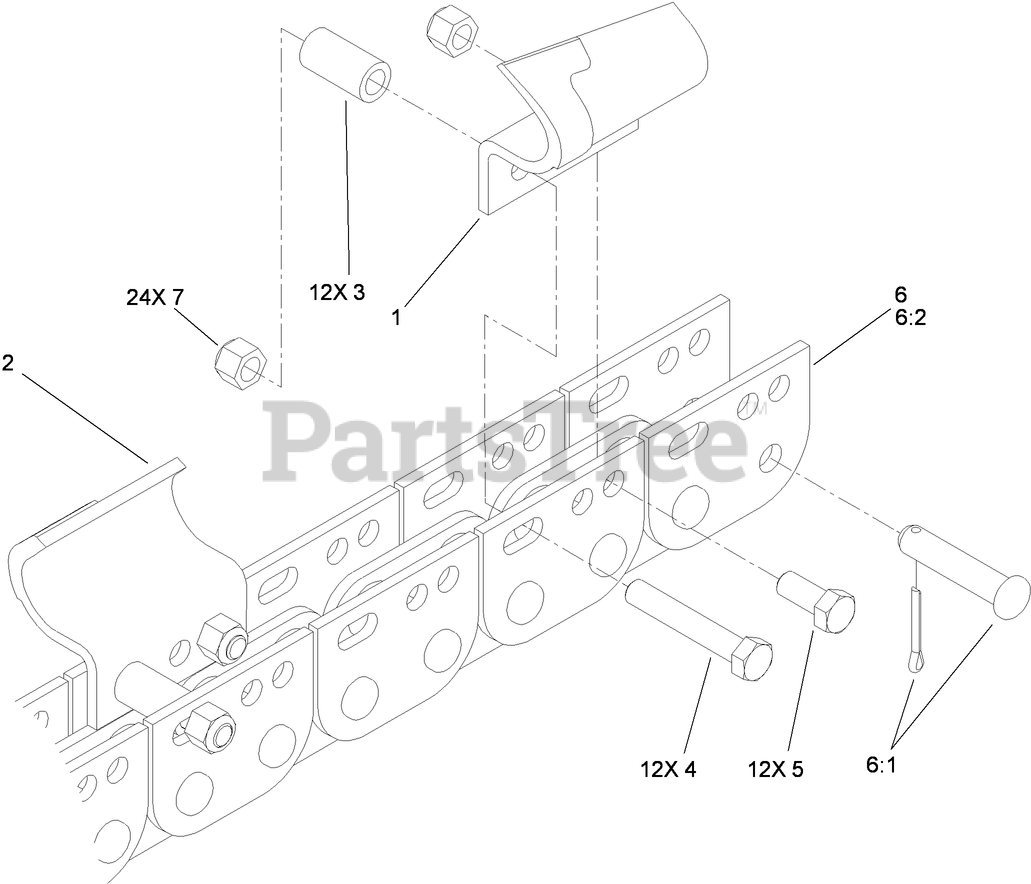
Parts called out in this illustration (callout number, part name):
1	TOOTH-SOIL, LH
2	TOOTH-SOIL, RH
3	SPACER-TUBE
4	SCREW-HH
5	SCREW-HH
6	CHAIN-BARE, 24 STATION
6:1	PIN-CONNECTING,
6:2	KIT-REPAIR, LINK
7	NUT-LOCK
